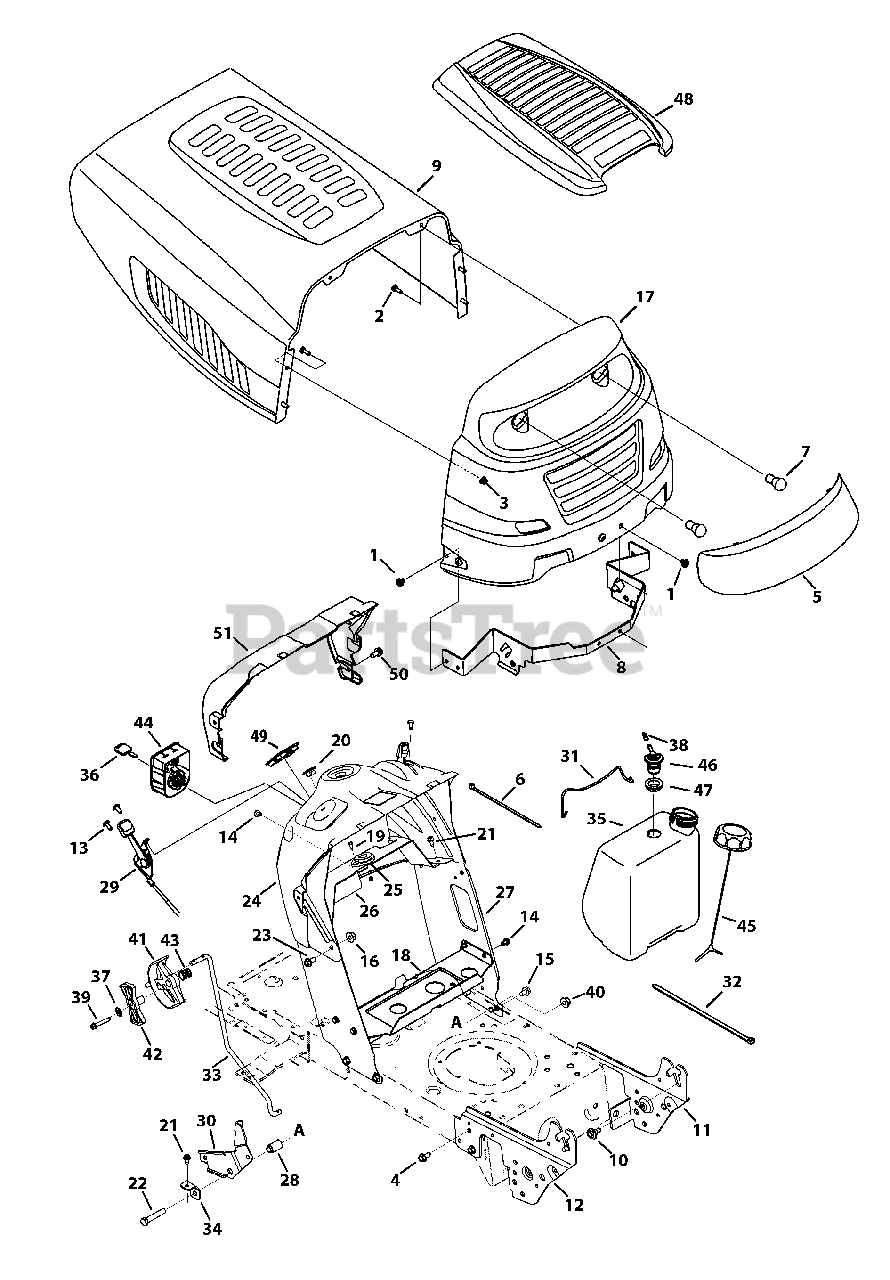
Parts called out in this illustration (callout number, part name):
1	Screw, 5/16-18 x .375
2	Hex Screw, 1/4-20 x .620
3	Flangelock Nut, 1/4-20
4	Screw, 5/16-18 x .750
5	Grill Lens
6	Cable Tie
8	Hood Pivot Bracket
9	Hood - Red
10	Shoulder Screw, 5/16-18 x .43 x .29
11	Left Support Pivot Bracket
12	Right Support Pivot Bracket
13	Screw, 1/4-20 x .500
14	Screw, 1/4-20 x .500
15	Screw, 5/16-18 x .625
16	Flangelock Nut, 5/16-18
17	Grille - Red
18	Gas Tank Support Bracket
19	Screw, #10-16 x .500
20	Choke Plug
21	Tap Screw, 1/4-20, 0.625
22	Hex Screw, 3/8-16 x 2.0
23	Hex Screw, 5/16-18 x .625
24	Dash, Upper NRMC
25	Bearing, .628 ID x 1.36
26	Bracket, Steering Support
27	Dash, Lower - Powder Black
28	Flange Spacer, .390 x .671 x 1.095
29	Throttle/Choke Cable
30	Speed Latch - No RMC
31	Battery Assembly Rod
32	Cable Tie
33	Speed Control Rod
34	Speed Latch Tab
35	1.36 Gallon Fuel Tank
36	Key, Assembly
37	Lock Washer, 1/4
38	Hose Vent, 3/16 EPA
39	Hex Washer Screw, 1/4-20 x 1.50
40	Flangelock Nut, 3/8-16
41	Shift Lever
42	Index Control
43	Compr. Spring, .72 OD x .78
44	Key Switch 3 Position
45	Fuel Cap, 2.25"
46	Rollover Valve
47	Rubber Grommet, 23 x 3.55
48	Hood cover
49	Ammeter Plug
50	Screw, 1/4-15 x .750
51	Dash Collar
